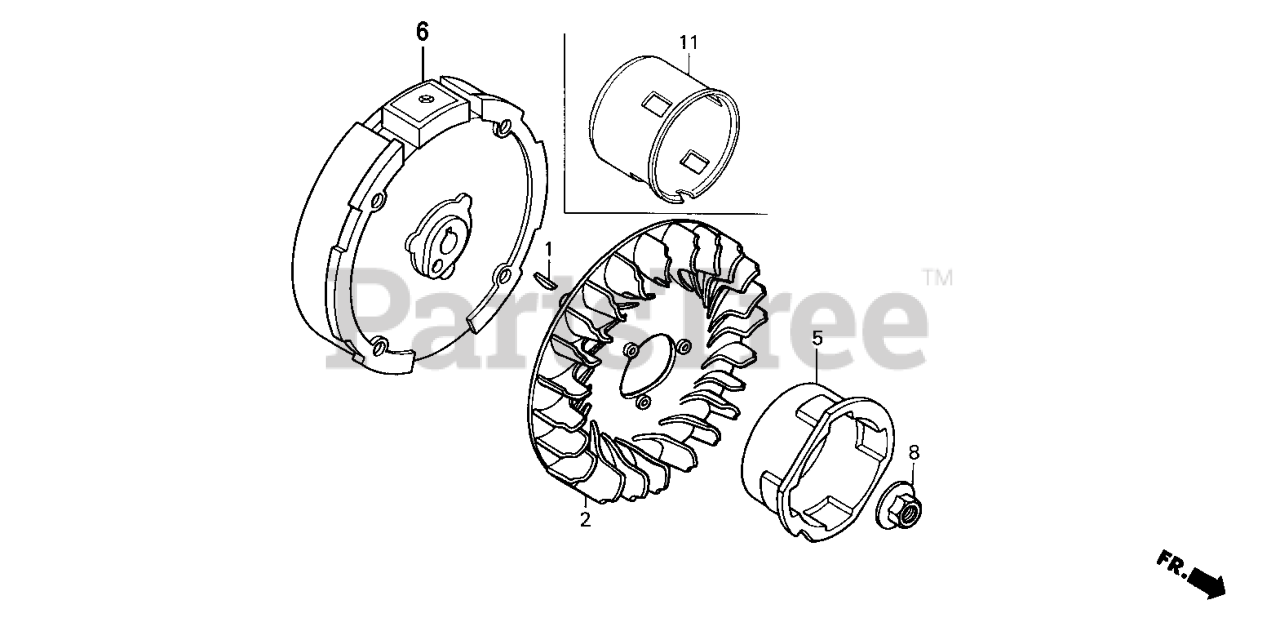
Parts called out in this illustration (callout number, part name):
1	KEY, SPECIAL WOODRUFF (25X18)
2	FAN, COOLING
4	PULLEY, STARTER
6	FLYWHEEL
8	NUT, SPECIAL (14MM)
